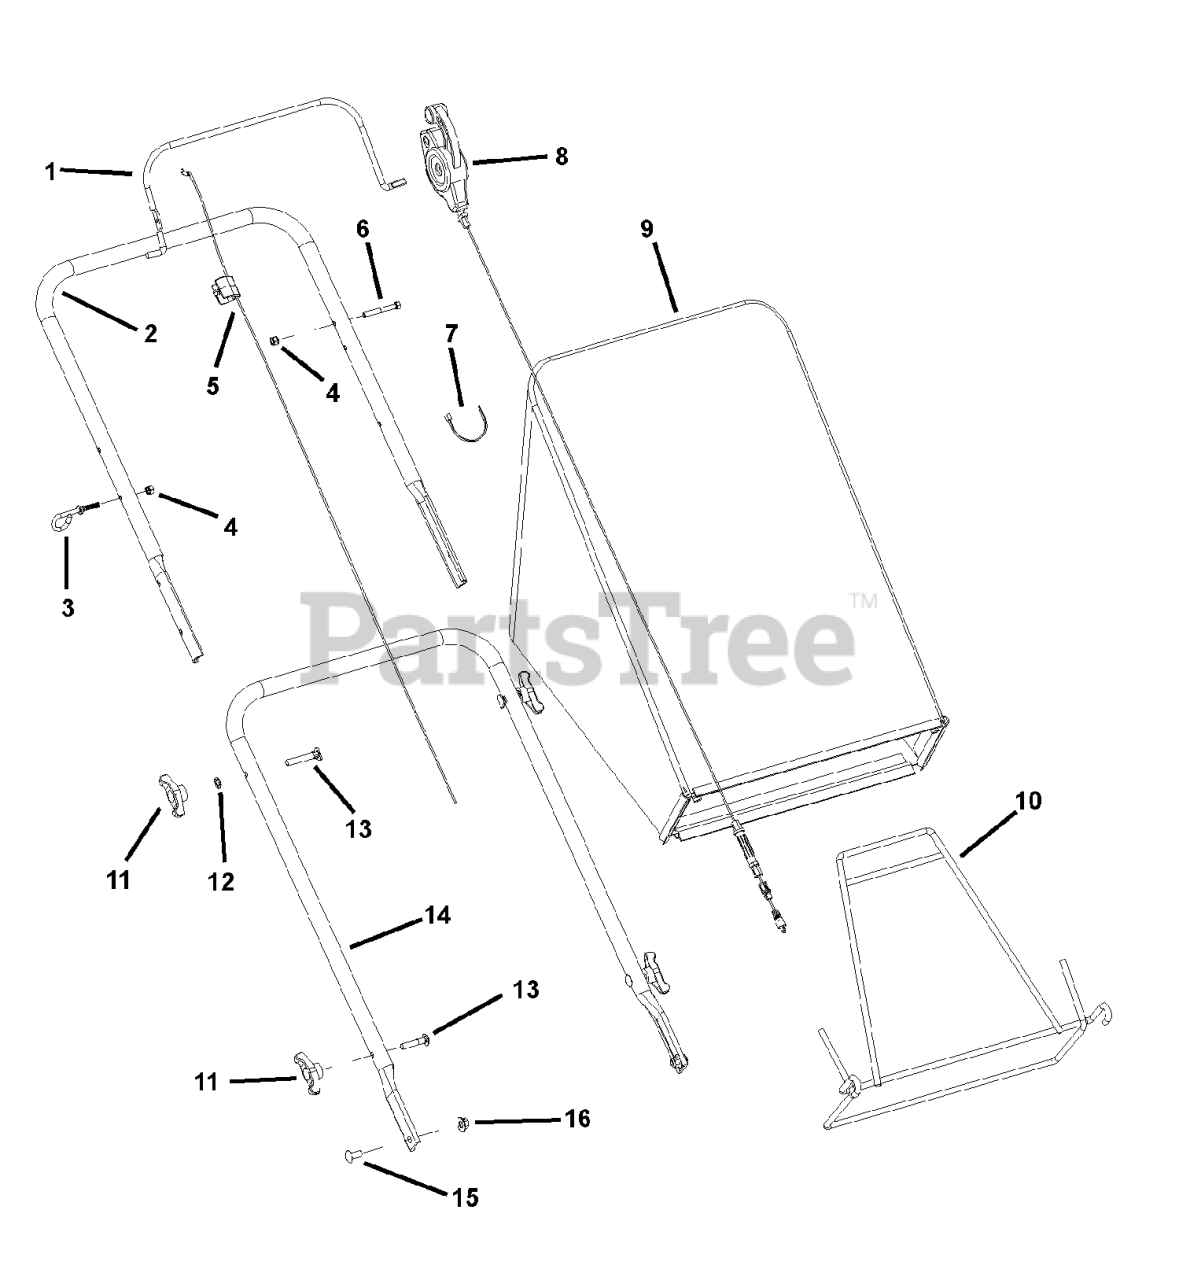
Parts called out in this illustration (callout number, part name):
1	BAIL, OPC PROPELLED
2	HANDLE, UPPER, PROPELLED
3	GUIDE, ROPE (1/4-20 thread)
4	NUT, HEX, 1/4C NYL RNG
5	CABLE, BAIL, HW PROPELLED
6	BOLT, HEX .25-20 X 2.00
7	WIRE TIE, 11 INCH STD BLK NYLON
8	CONTROL, DRIVE, SINGLE SPEED
9	GRASS BAG ASSEMBLY, CLOTH (incl. next 2 items below)
10	WELDMENT, FRAME, GRASS BAG
11	KNOB, 5/16-18 WING (BLACK)
12	LOCKWASHER, 5/16
13	BOLT, 5/16-18 X 2 GR2
14	HANDLE, LOWER
15	BOLT, 5/16-18 X 3/4 GR5 YZ
16	NUT, HEX, 5/16-18 BLACK
